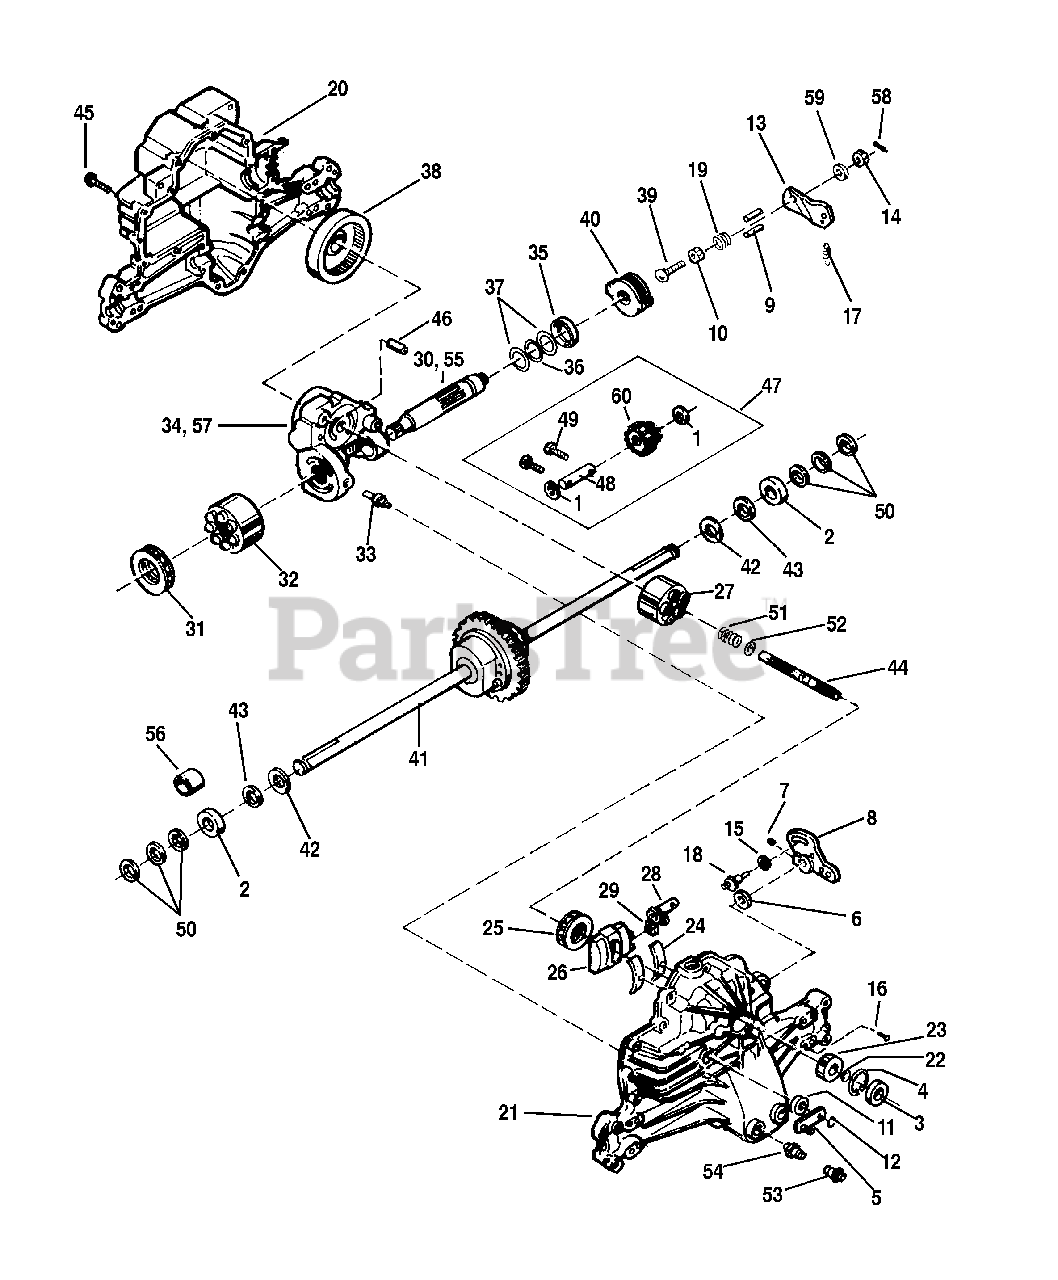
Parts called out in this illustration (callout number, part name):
1	WASHER, 7/16 x 1 x 1/2
2	BALL BEARING
4	RETAINING RING
5	ARM, Bypass
8	ARM, Control
9	PIN, Actuating
10	NUT, Hex, Lock, 5/16-24
12	RETAINING RING
13	ARM, Actuating
14	CASTLE NUT, 5/16-24
15	PUCK, Dampener
17	SPRING, Extension
18	STUD, 5/16-24
19	SPRING, Compression
20	HOUSING, Lower
21	HOUSING, Upper
23	BALL BEARING, Shaft
24	BEARING, Cradle
25	BEARING, Thrust
27	BLOCK, Cylinder
28	ARM, Trunnion
29	GUIDE, Slot
30	SHAFT, Motor
31	BEARING, Thrust
32	BLOCK, Cylinder
33	ACTUATOR, Bypass
34	CENTER SECTION ASSY.
36	RETAINING RING
37	WASHER, 17/64 x 23/64 x 1
38	ELEMENT, Oil Filter
39	BOLT, 5/16-18 x 1-3/4
40	BRAKE ROTOR/STATOR KIT
41	DIFFERENTIAL ASSY.
42	WASHER, 3/4 X 1-1/2 X 1/32
43	SEAL, 3/4 X 1-1/4 X 1/4
44	SHAFT, Input
45	BOLT, 1/4-20 x 1-3/8
46	PIN, 1/2 O.D. x 7/16 I.D. x 3/4
47	JACK SHAFT/PINION GEAR ASSY.
49	CAPSCREW, 6mm x 13/64
50	SEAL, Wiper
51	SPRING, Block
52	WASHER, Block Thrust
53	VENT CAP ASSY.
54	FITTING & O-RING ASSY.
55	SHAFT, Motor
56	SLEEVE BEARING
57	CENTER SECTION ASSY.
58	COTTER PIN
59	WASHER, 7/16 x 7/8 x 51/64
